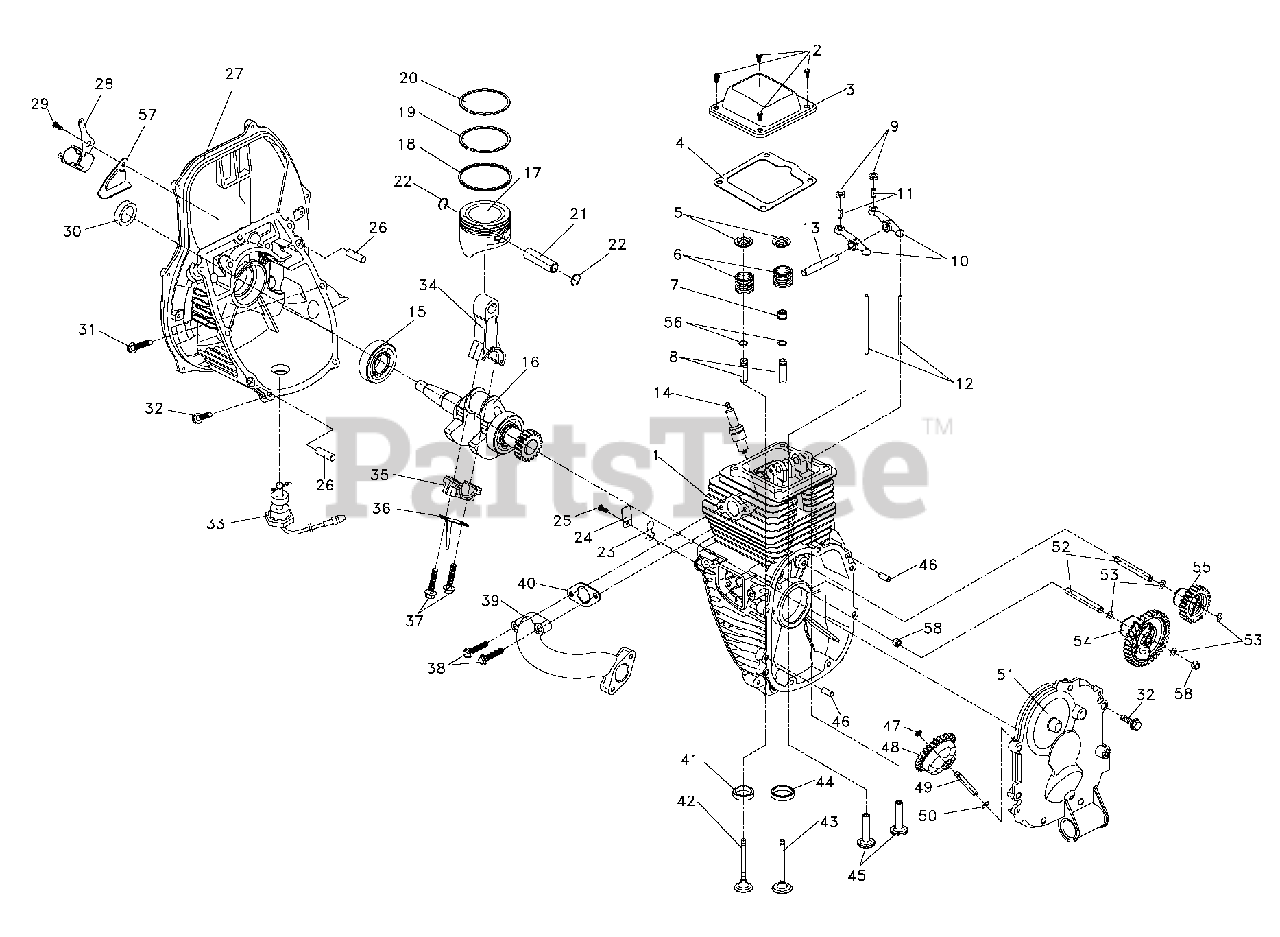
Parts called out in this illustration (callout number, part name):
4	GASKET, VALVE COVER
12	PUSH-ROD, VALVE
14	SPARK PLUG
15	BEARING, BALL
16	CRANKSHAFT
21	PIN, PISTON
22	CIRCLIP, PISTON PIN
26	GUIDE PIN, CASE BODY, 8X26
27	COVER, CRANKSHAFT TANK
28	TRIGGER ASSY.
29	SCREW, PHILLIPS W/WASHER, M5X12
30	OIL SEAL, CRANKSHAFT
31	BOLT, HEX, FLANGE, M6X45
32	BOLT, HEX, FLANGE, M6X25
33	SENSOR ASSY., OIL
38	BOLT, HEX. FLANGE, M6X30
39	PIPE, EXHAUST
40	GASKET, EXHAUST PIPE
45	TAPPET, VALVE
52	PIN, CAMSHAFT
53	GASKET, CAMSHAFT
54	GEAR ASSY, EXH. VALVE CAMSHAFT
55	GEAR ASSY, INLET VALVE CAMSHAFT
57	PLATE, PRESSURE
58	BEARING, OIL RETAINER
